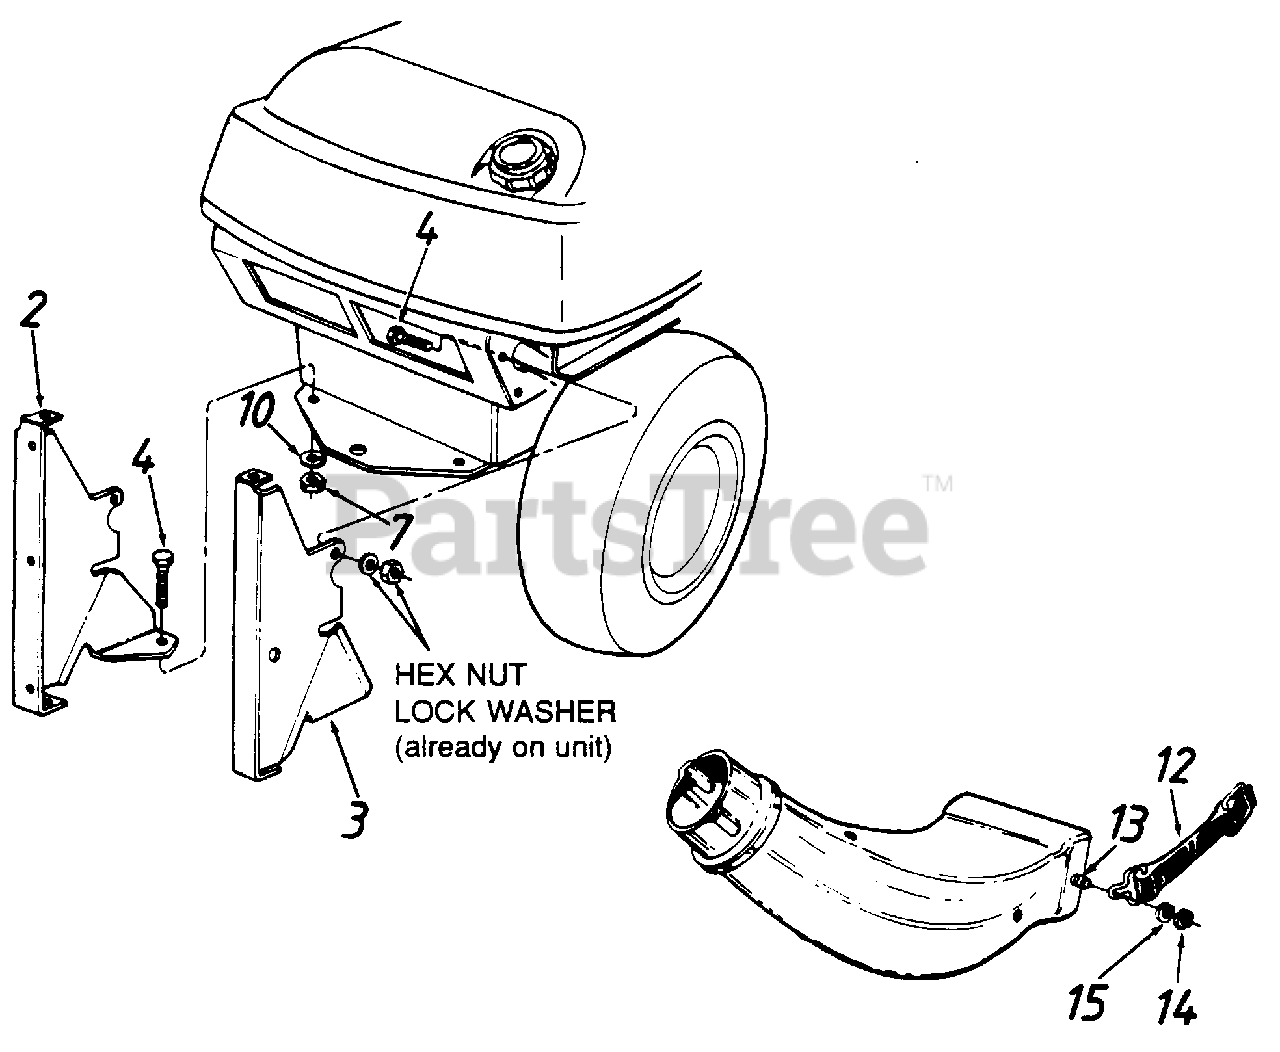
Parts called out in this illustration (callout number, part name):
2	Catcher Support Brkt. - R.H.
3	Catcher Support Brkt. - L.H.
4	Hex Bolt 5/16-18 x 1.0" 4.
7	Hex Nut 5/16-18 Thd.
10	L-Wash. 5/16 I.D.
12	Strap
13	Screw
15	Washer
